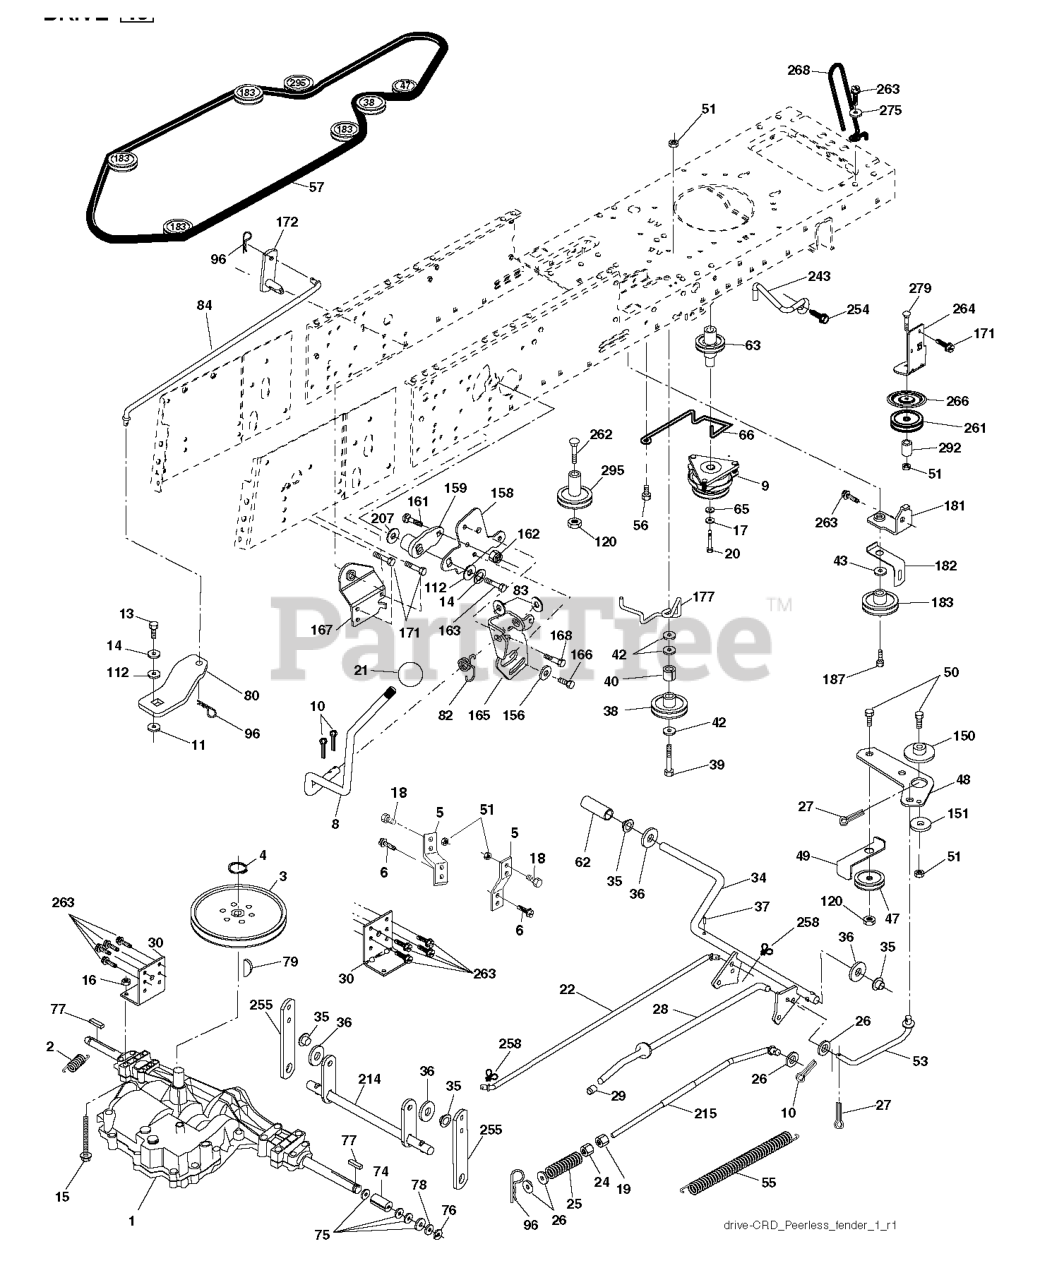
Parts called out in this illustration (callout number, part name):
2	SPRING,BRAKE RETURN
3	PULLEY
4	RETAINING RING LT
5	STRAP TORQUE
6	SCREW 5/16"
8	ROD SHIFT FENDER ADJUST LT
9	CLUTCH.ELECTRIC.OGURA.EURO.
10	PIN COTTER
11	WASH-SHFT PLT LT
13	BOLT 1/4-28X3/4
14	LOCKWASHER
15	BOLT HEX 5/16-18 GR 5
16	NUT.71038.31-18.HEX.NYLOCK
19	NUT
20	BOLT HEX 7/16-20X4-1/4"
21	KNOB.DUCKHEAD.1/2
22	ROD
24	NUT
25	SPRING ROD LT
26	WASHER
27	COTTER PIN
28	ROD, PARKING BRAKE
29	CAP
30	BRKT, MOUNT TRNSAXLE
34	SHAFT, FOOT PEDAL
35	BEARING.NYLON
37	DRIVE PIN
38	PULLEY.FLAT
42	WASHER
47	IDLER PULLEY
48	BELLCRANK, CLUTCH
49	RETAIN BELT
50	BOLT.3/8-16X1.50
53	LINK.CLUTCH.7.66.2005
55	SPRING, RETURN LT
56	SCREW.3/8-16
57	V-BELT.KEV.111"
62	PEDAL COVER T
63	PULLEY.ENGINE.CVX.LT
65	LOCKWASHER
66	KEEPER BELT ENGINE
74	SPACER AXLE
77	SQUARE KEY
79	KEY STD (1373) DANA
82	SHIFT SPRING
83	WASHER
96	RETAINER M
120	NUT LOCK FLG 3/8-16 UNC
150	BUSHING.BELLCRANK.GRD.DR
151	WASHER 12/32X2X10GA
156	WASHER.SRRTD.5/16
158	BRACKET
159	RB HUB.SHIFT
161	BOLT
162	NUT.CROWNLOCK.1/4
165	RP BRACKET
166	CAPSCREW.HXHD.FLG.5/16-18X.625
167	BRACKET.SUPT.SHIFT.CRD
168	BOLT.SHOULDER.5/16-18X
172	SHAFT
181	BRACKET
182	BELT GUIDE
183	PULLEY.V-IDLER.GRND.DR
187	BOLT.5/16-18X1.25
207	WASHER NYL
214	LEVER
243	BRACKET, ANTI-ROTATION
254	SCREW 3/8-16X1
255	SHAFT
258	CLIP RETAINER
261	FLAT IDLER PULLEY
263	SCREW, 3/8-16X3/4
266	PROTECTOR
268	GUARD MUFFLER
275	WASHER
292	SPACER
295	PULLEY IDLER COMPOSITE
